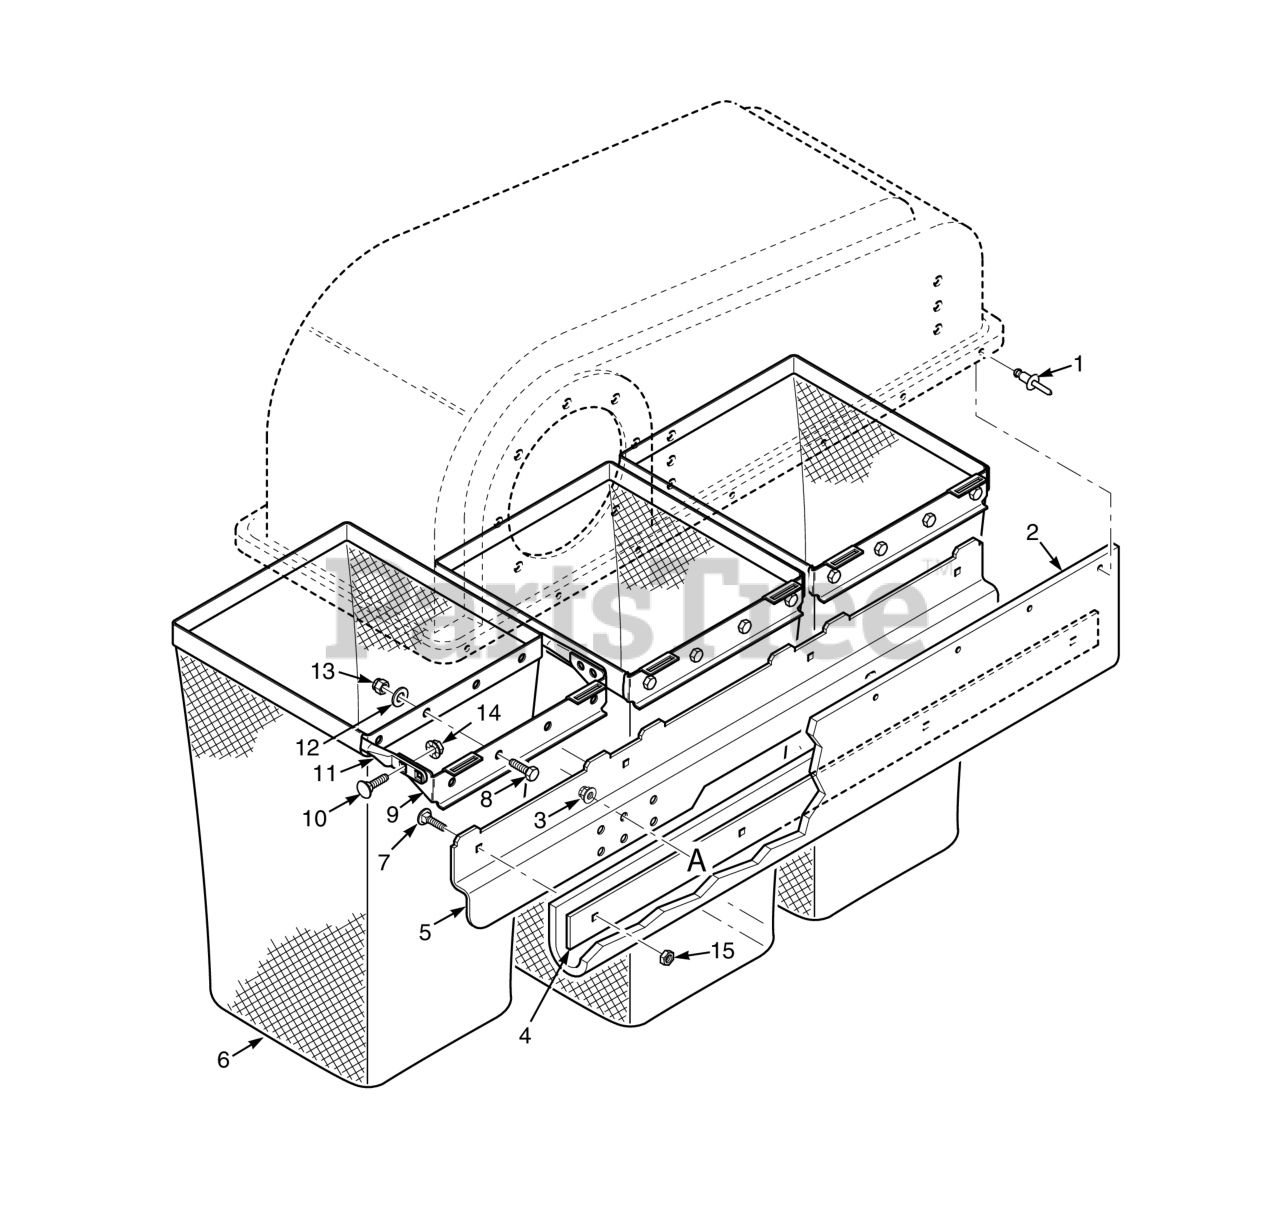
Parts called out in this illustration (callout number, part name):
1	Pop Rivet, 3/16 x .652"
2	Seal, Hood
3	Nut, Flange Elastic Stop Nut, 3/8-16
4	Retainer, Seal
5	Support Weldment, Bag Frame
6	BAG ASSY, GC
7	Serr. Fl. Hex Head CPSCR, 1/4-20 x 3/4"
8	BOLT, SERRATED FLANGE HEX HEAD 5/16-18 X 3/4"
9	Mount, Bag Frame Tube
10	Bolt, 5/16-18 x .75 RHSN Carriage
11	Tube, Bag Support
12	Flatwasher, 5/16-.375 x .875 x .083 (35BV & 37BV-EFI)
13	HEX NUT, ELASTIC STOP LOCK, 5/16-18
14	Nut, Serrated Flange 5/16-18 (Right Front Engine Mounting, Briggs and Kohler Only)
